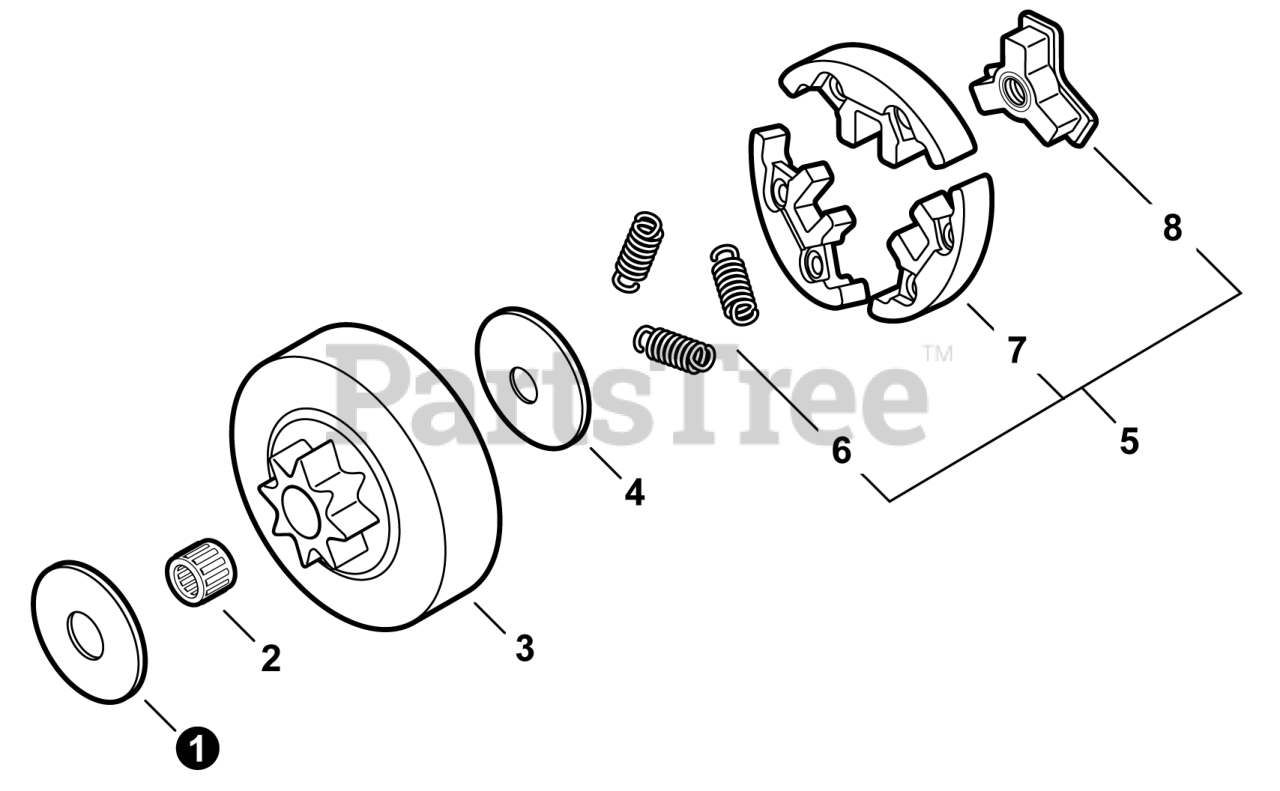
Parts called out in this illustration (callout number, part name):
1	WASHER 10
2	BEARING, NEEDLE 10
3	DRUM, CLUTCH
4	PLATE, CLUTCH
5	CLUTCH ASSY
6	SPRING, TENSION
7	CLUTCH SHOE SET (3PCS)
8	HUB, CLUTCH
